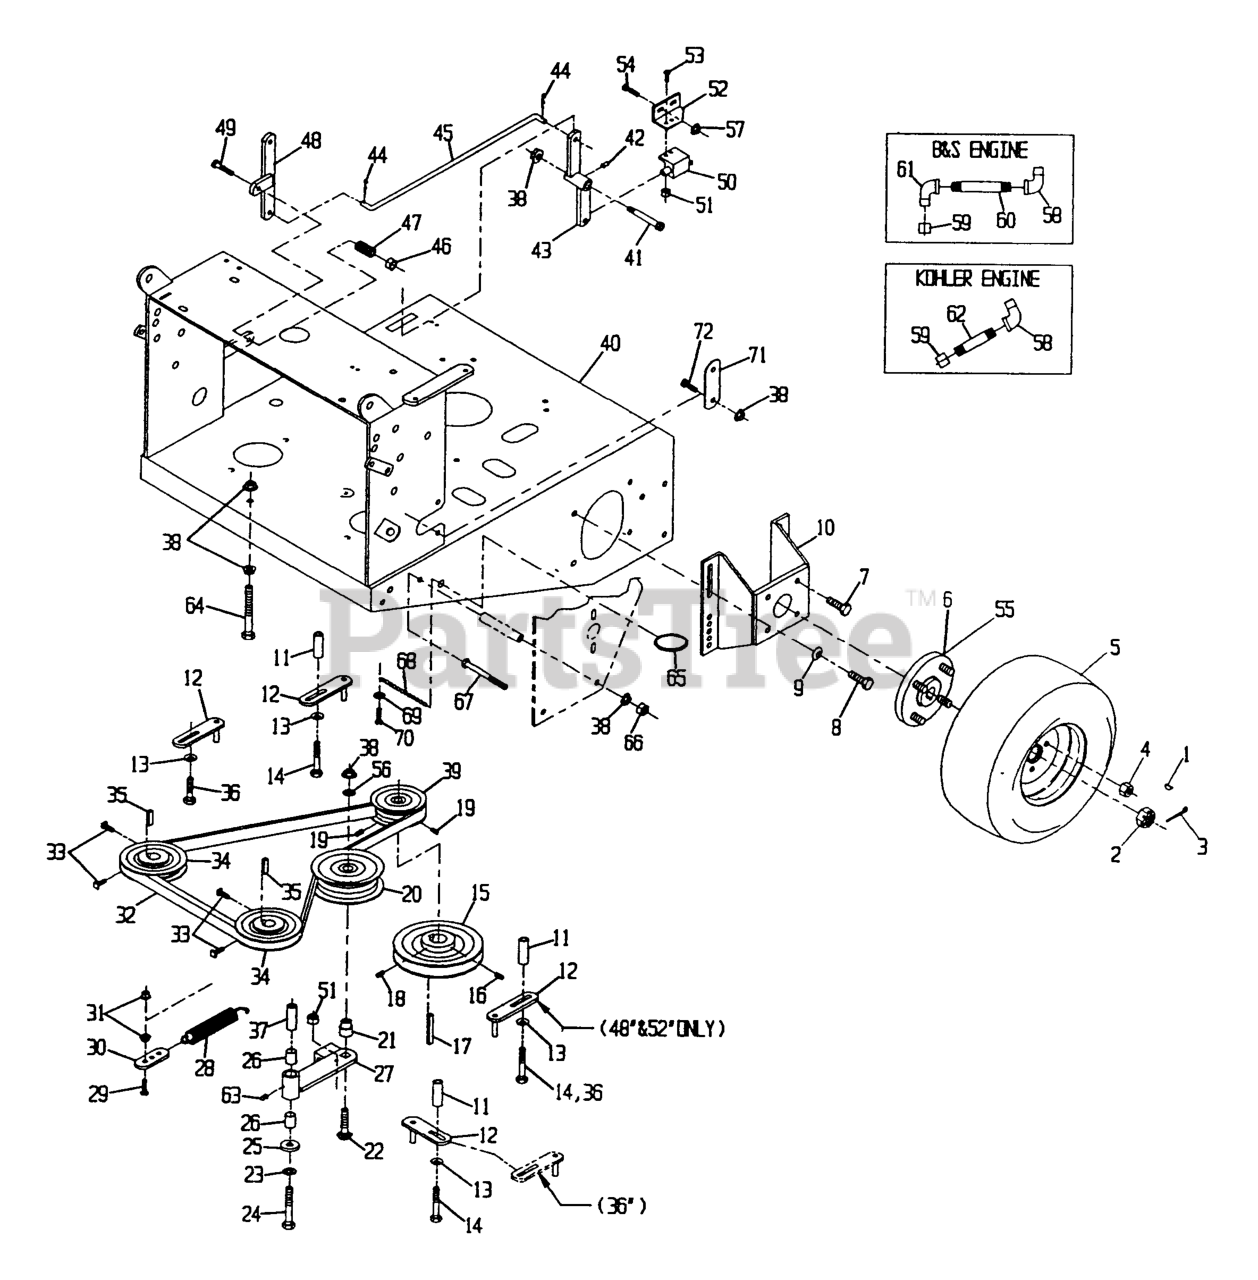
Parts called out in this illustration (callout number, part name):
1	KEY-WOODRUFF
3	PIN-COTTER
10	MOUNT-MOTOR
12	GUIDE-BELT
13	WASHER-SPRING
14	SCRW,CAP HH M8X1.25X75M
17	KEY,MACH 1/4X1/4X2-5/8
18	SCREW-SET
19	SCREW-SET
21	BUSHING-IDLER
26	SLEEVE-BEARING
27	IDLER ARM ASM
28	SPRING-EXTENSION
30	ANCHOR-SPRING
32	BELT,HYDRO TRANS DRIVE
33	SCREW-SET
34	SHEAVE - PUMP
37	BUSHING
43	BELLCRANK ASM
44	PIN-COTTER
45	LINKAGE-ENGAGE, BLADE
47	SPRING-COMPRESSION
50	SWITCH-OPEN, NORMALLY
52	BRACKET-SWITCH, BLADE
58	FITTING-ELBOW-90
59	CAP-HEX
60	NIPPLE
61	ELBOW-90 DEG
62	NIPPLE
65	RING-SPLIT
68	CHAIN-LINK, TWIST
70	SCREW-HSH
71	ARM-LIFT, DECK
